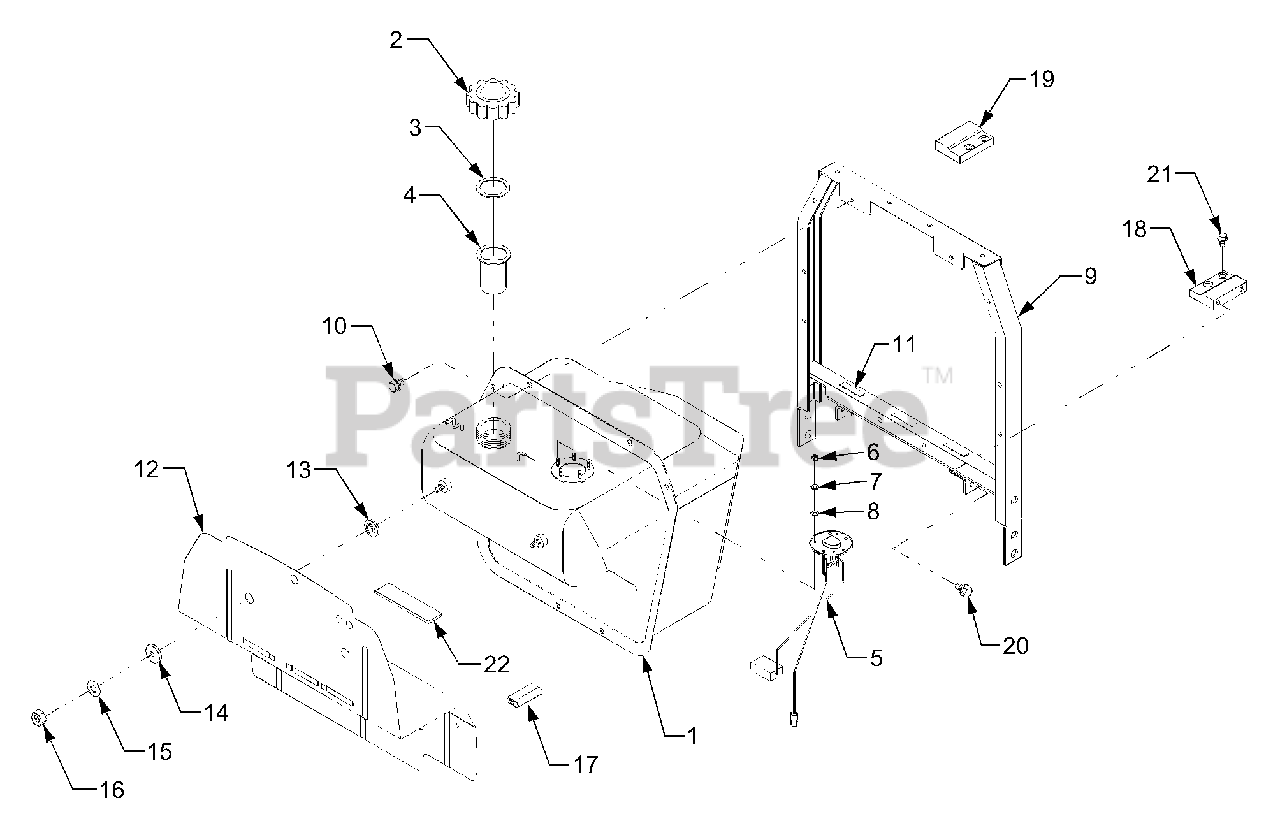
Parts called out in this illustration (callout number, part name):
1	Tank, Fuel
2	Fuel Cap Assy
4	Strainer, Fuel
5	Fuel Sender Ass'y
7	Washer, Spring
8	Washer, Plain
9	Bracket, Bonnet
11	Rubber, Cushion
12	Plate, Shuttle
15	Washer, Plain
22	Rubber Cushion
